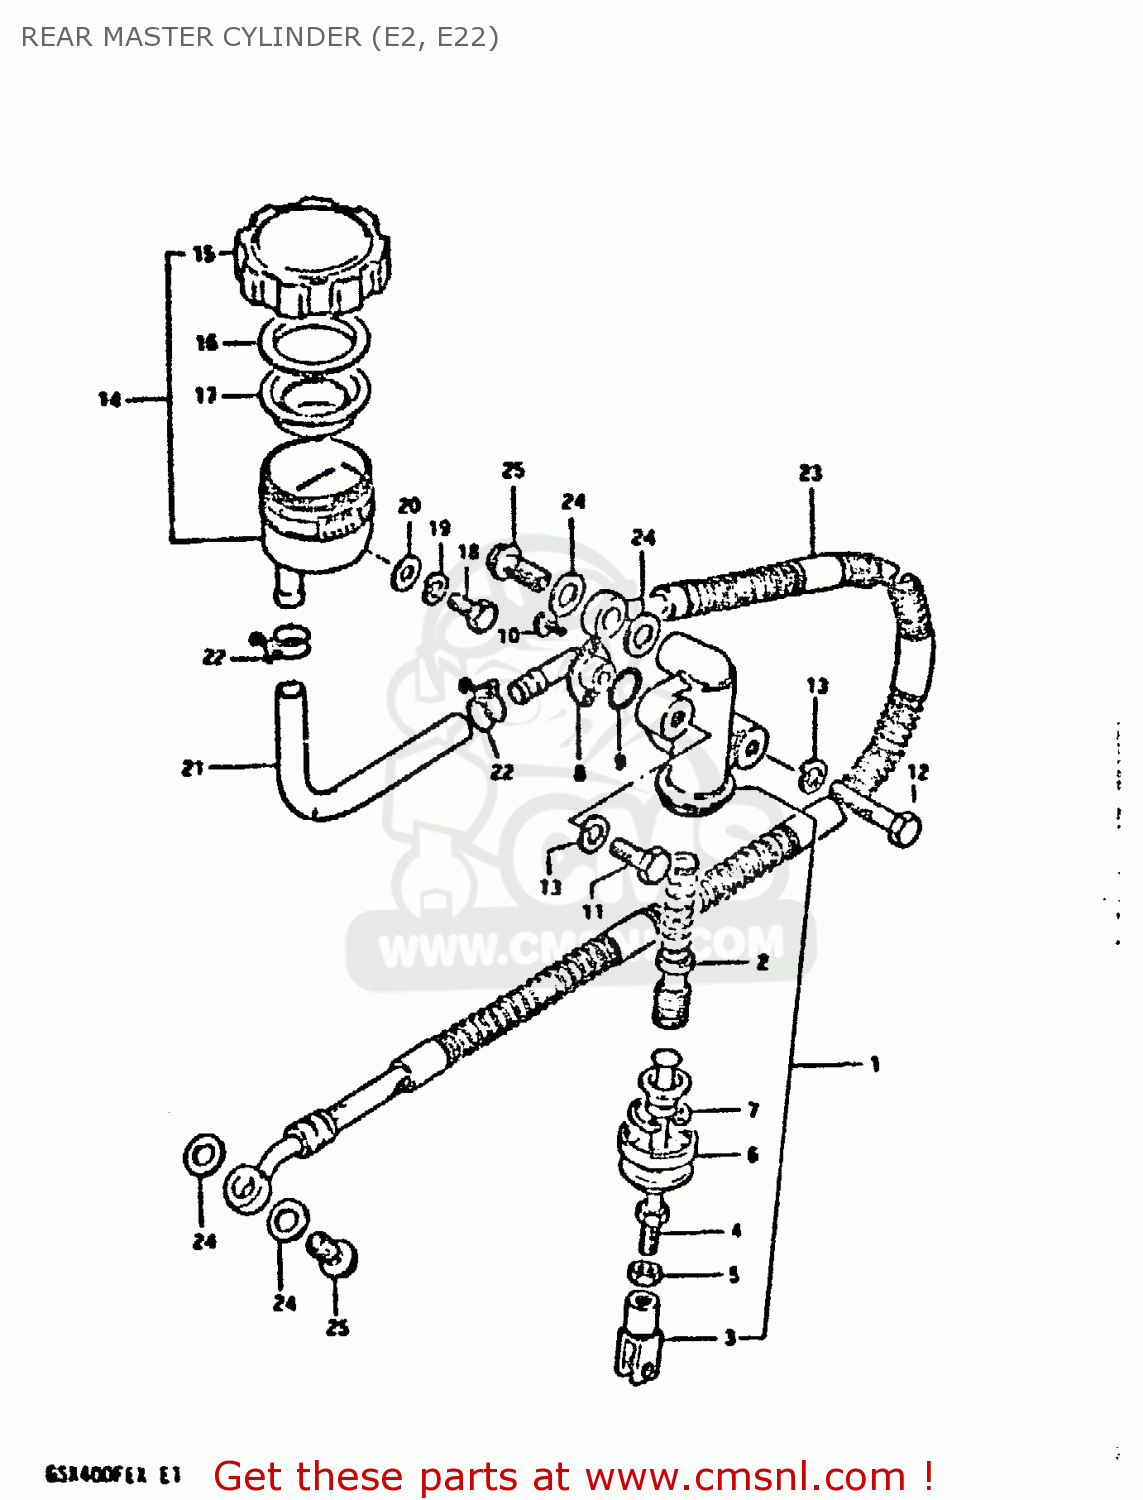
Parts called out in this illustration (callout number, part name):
1	CYLINDER ASSEMBLY,REAR MASTER
2	PISTON & CUP SET
3	YOKE
4	ROD,REAR MASTER CYLINDER
5	NUT
6	REAR BRAKE MASTER CYLINDER GSX 400
7	CIRCLIP
8	CONNECTOR,HOSE
9	O RING
10	SCREW
11	BOLT
12	BOLT 8X55
13	LOCK WASHER
14	TANK ASSEMBLY,RESERVOIR
15	CAP
16	PLATE,DIAPHRAGM
17	DIAPHRAGM
18	BOLT, UPPER
19	LOCK WASHER
20	WASHER
21	HOSE
22	CLAMP
23	HOSE, REAR BRAKE
24	WASHER
25	BOLT,UNION
